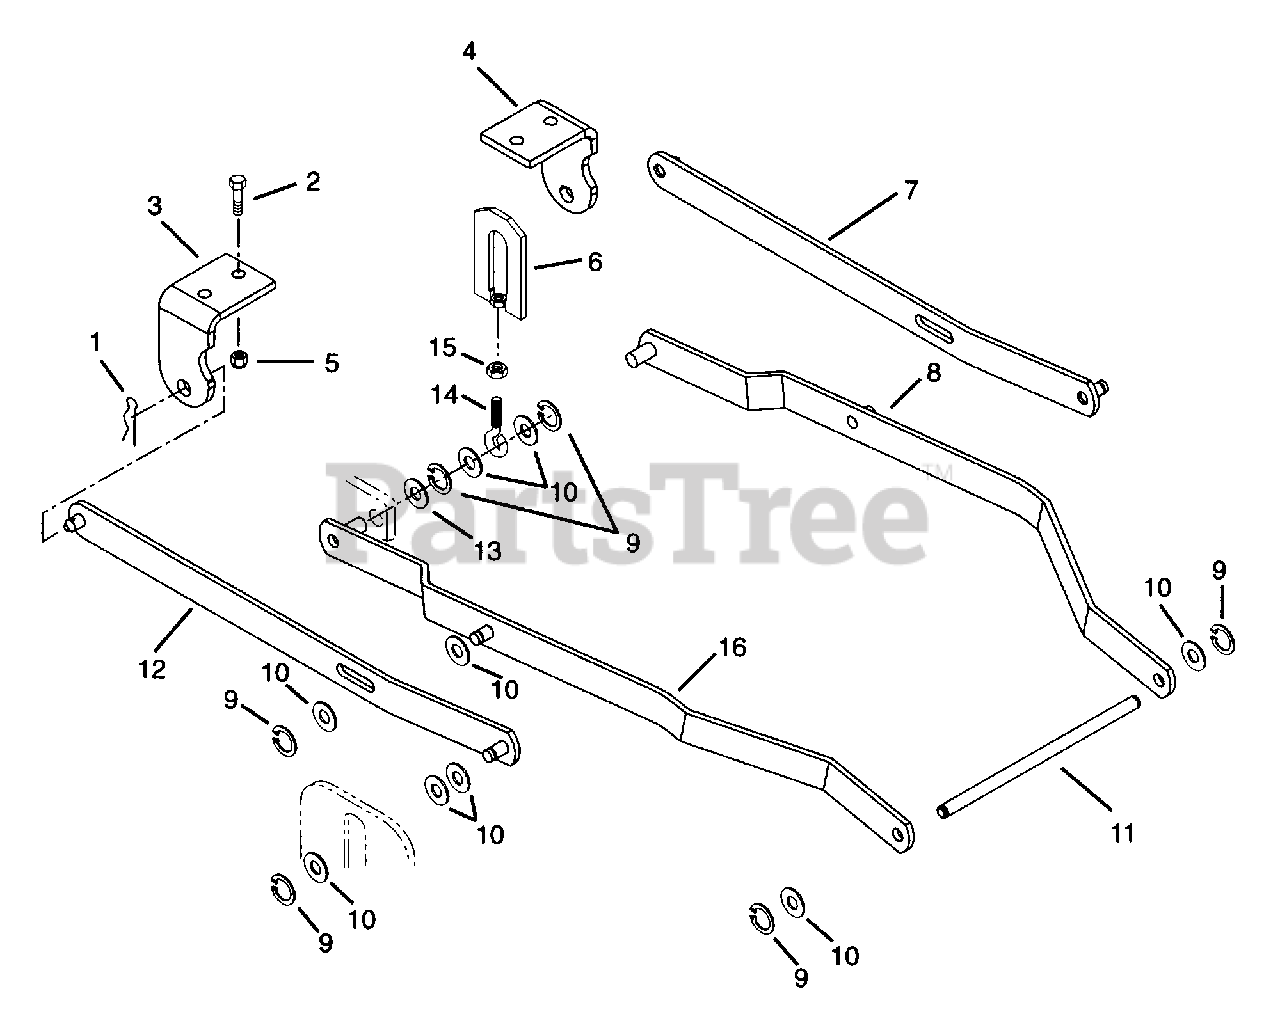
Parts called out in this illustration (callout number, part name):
1	PIN-HAIR EXT .12X.31X2.37 PL
2	BLT-HEX .38-16X1.00 PL GR5
3	RH REAR HANGER
4	REAR HANGER
5	NUT-LK-NYL .375-16 PL
6	LINK, ADJUSTMENT
7	REAR HANGER LH
8	LH LIFT ARM
9	RG-RTNG-EXT .500X.050 (SNAP)
10	WSHR-FL-STL .531X1.062X.095 PL
11	PIN
12	REAR HANGER RH
13	WSHR-FL-STL .531X1.250X.100 PL
15	NUT-JAM .375-16 PL
16	RH LIFT ARM
